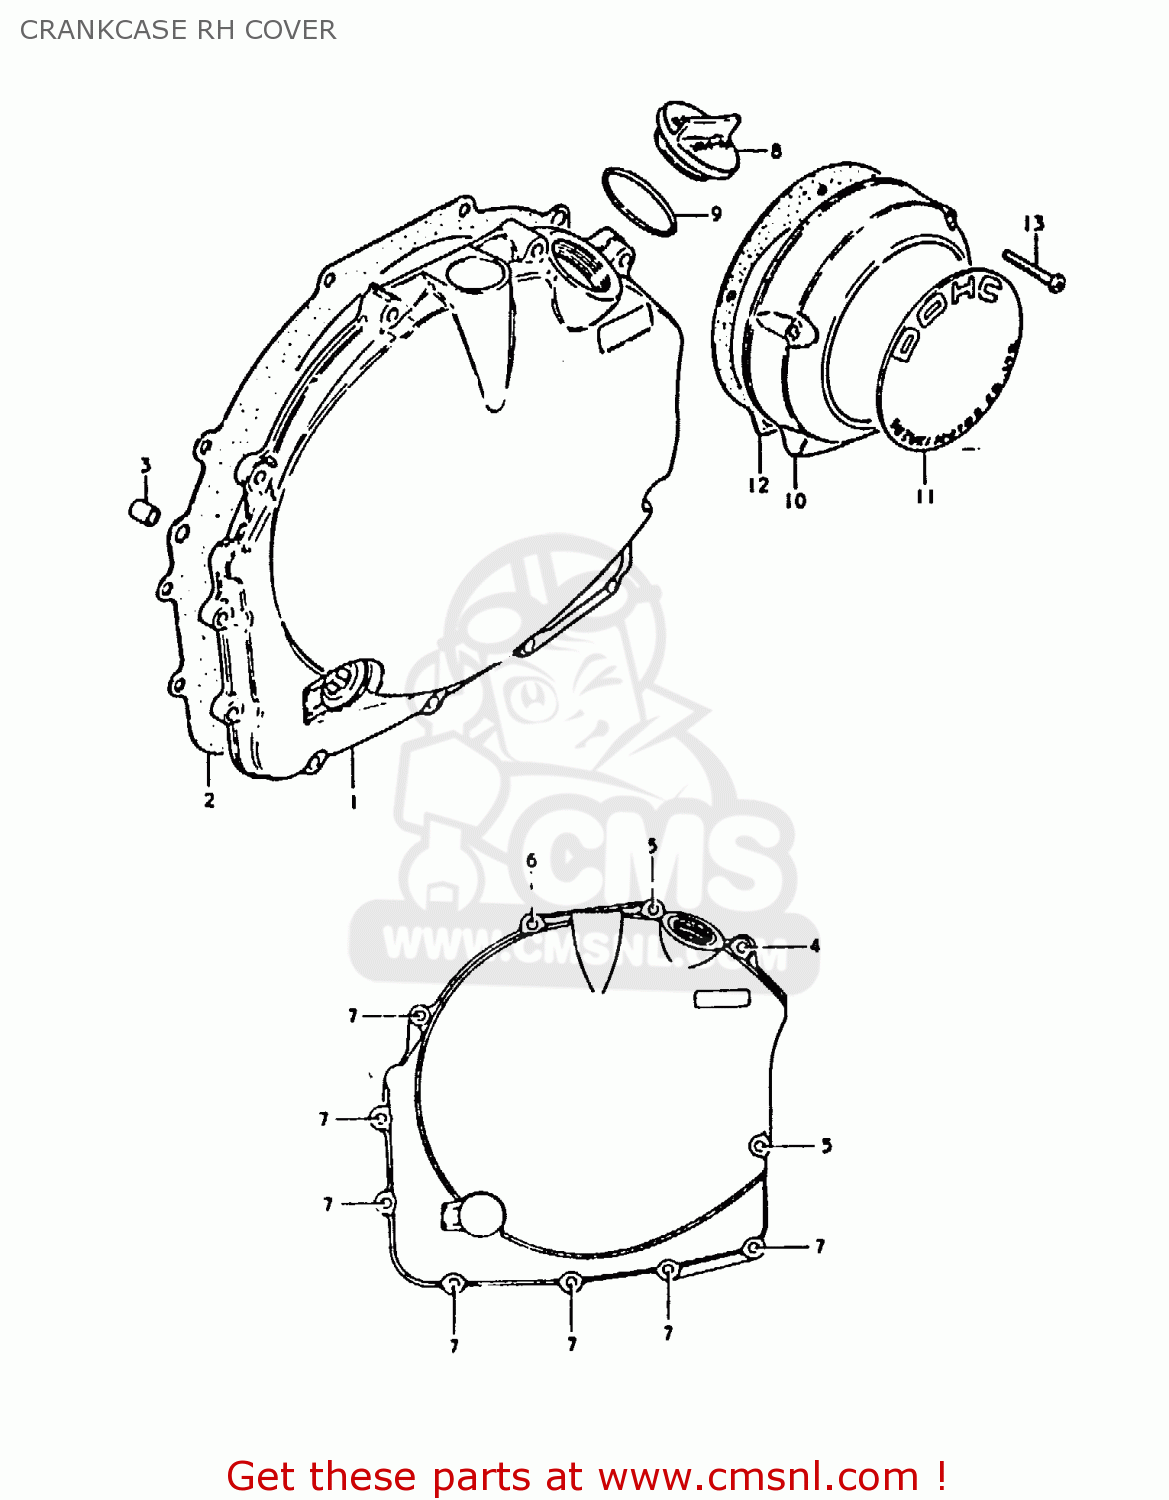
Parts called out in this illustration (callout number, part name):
1	COVER,CLUTCH
2	GASKET,CLUTCH COVER (MCA)
3	PIN
4	SCREW (6X35)
5	SCREW
6	SCREW
7	SCREW
8	CAP
9	O RING(D:2.2,ID:32)
10	COVER,CONTACT BREAKER
11	EMBLEM
12	GASKET,CONTACT BREAKER COVER (NAS)
13	SCREW
